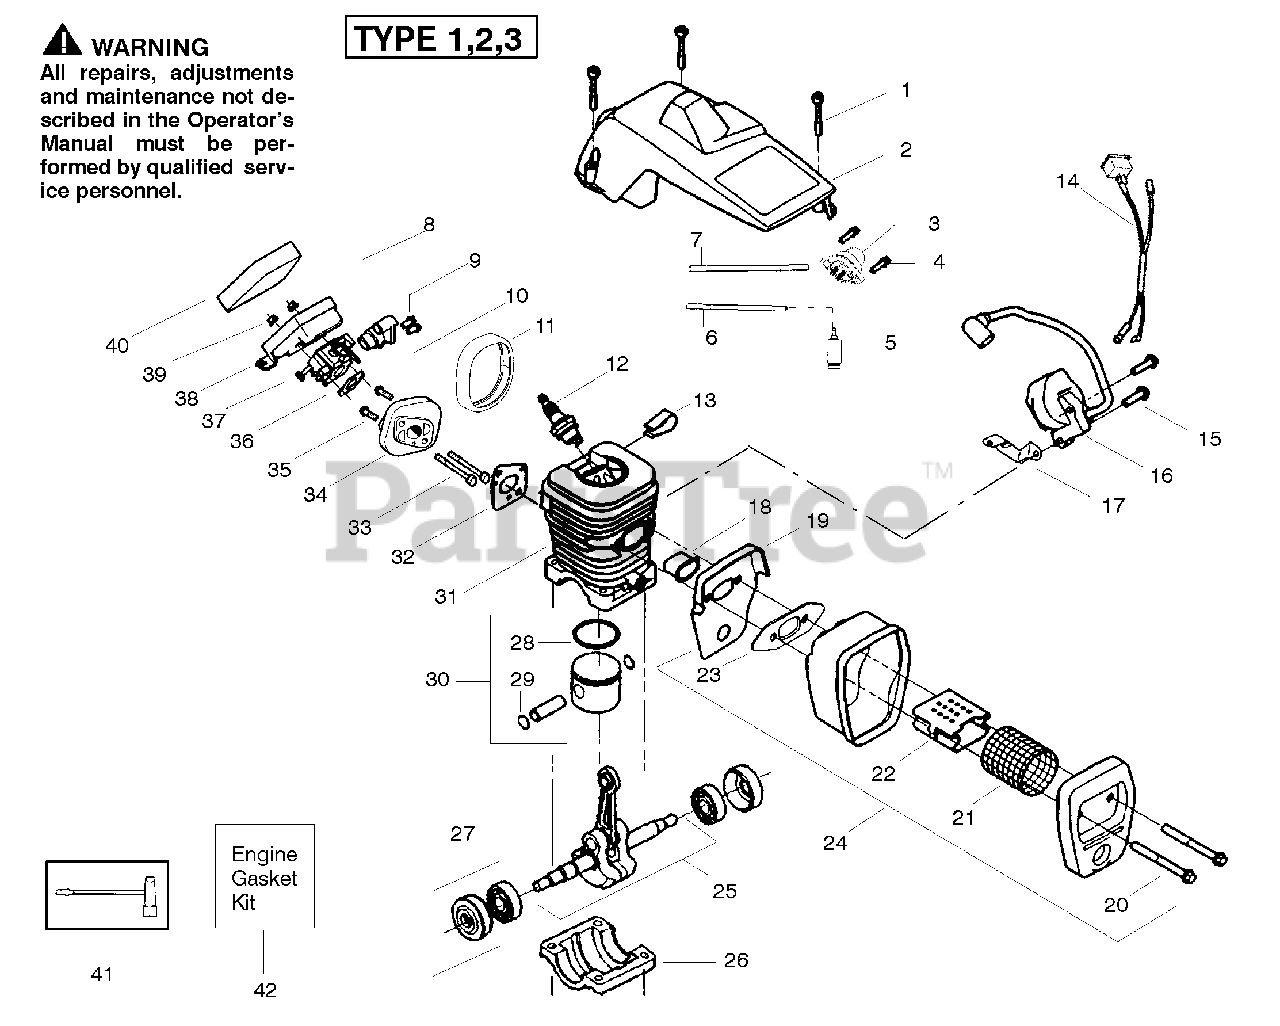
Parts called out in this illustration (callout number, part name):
2	Cylinder Shield
3	Air Purge Ass'y.
5	Fuel Pick-up Ass'y.
6	Kit-Line Purge/Carb. (Small Dia)
7	Kit-Line Purge/Tank (large line)
8	Grommet-Carb Adjust.
9	Limiter Cap-High
10	Limiter Cap-Low
11	Seal-Carb Adapter
12	Spark Plug (RCJ-7Y)
13	Clip-High Tension Lead
14	Wire Harness Ass'y.
15	Screw
16	Ignition Module, Walbro
16	Ignition Module, Phelon
17	Ground Strap
18	Heat Insulator
19	Muffler Back Plate
21	Spark Screen
22	Muffler Diffuser
23	Muffler Gasket
24	Muffler Ass'y.
25	Crankshaft Assy.
26	Cap-Crankcase
27	Seal & Bearing Assy.
28	Piston Ring
29	Retainer - Piston Pin
30	Piston Kit
31	Cylinder Kit
32	Gasket - Carb. Adapter
34	Carb. Adapter Kit
36	Carb. Gasket
37	Carburetor Kit
38	Air Filter Housing
40	Air Filter - Foam
41	Scrench
42	Engine Gasket Kit
